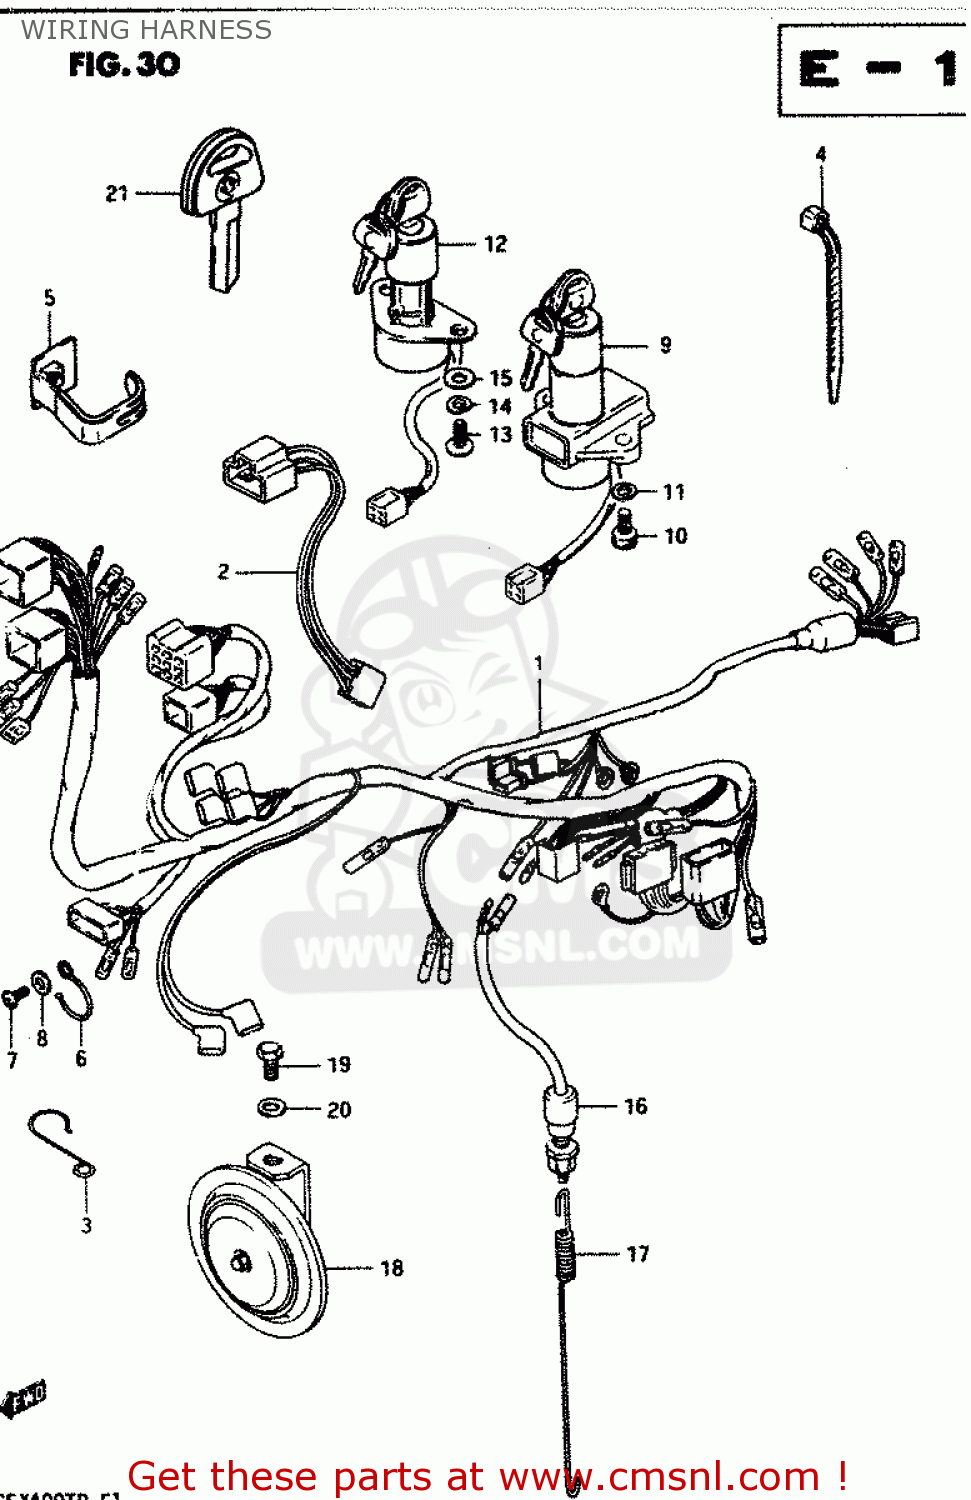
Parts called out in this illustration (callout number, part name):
1	HARNESS,WIRING
2	LEAD WIRE,HEADLAMP
3	CLIP,WIRING HARNESS
4	CLAMP(L:125)
5	CLAMP,WIRING HARNESS
6	CLIP,WIRING HARNESS
7	SCREW 6X12
8	WASHER
9	SWITCH ASSY,IGNITION
10	BOLT
11	LOCK WASHER
12	SWITCH ASSY, IGNITION
13	SCREW
14	LOCK WASHER
15	WASHER
16	SWITCH ASSEMBLY,STOP LAMP
17	SPRING
18	HORN ASSEMBLY
19	BOLT 8X12
20	WASHER
21	KEY,BLANK
